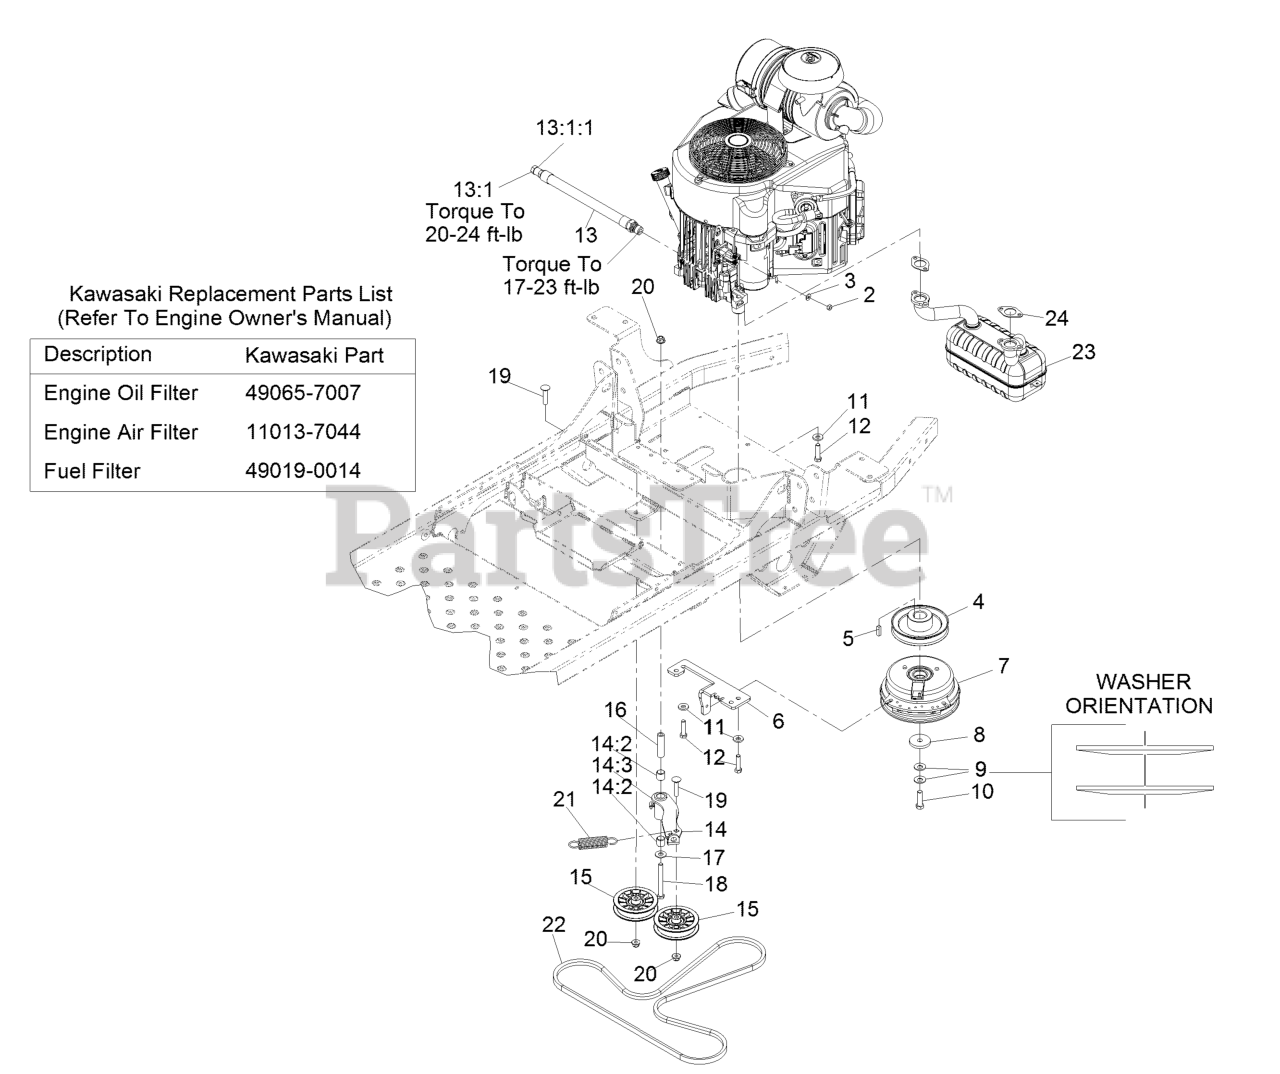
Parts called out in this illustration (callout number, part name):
2	NUT-HEX
3	WASHER-FLAT
4	SHEAVE-PUMP, DRIVE
6	ANCHOR-CLUTCH
8	WASHER-CLUTCH
9	WASHER-SPRING
10	SCREW-HH 7/16-20 X 1 1/2 W/LOCTITE
11	WASHER-BELLEVILLE
12	SCREW-HH
13	ENGINE OIL DRAIN HOSE ASM
13:1	PLUG-HH
13:1:1	O-RING
14:2	SLEEVE-BEARING
14:3	FITTING-GREASE, 90 DEG
15	PULLEY-FLAT IDLER
16	BUSHING-PIVOT, IDLER
17	WASHER-FLAT
18	SCREW-CARR
19	SCREW-CARR
20	NUT-HF, NI
21	SPRING-EXTENSION
22	V-BELT
23	MUFFLER-KAWASAKI
24	GASKET-EXHAUST
